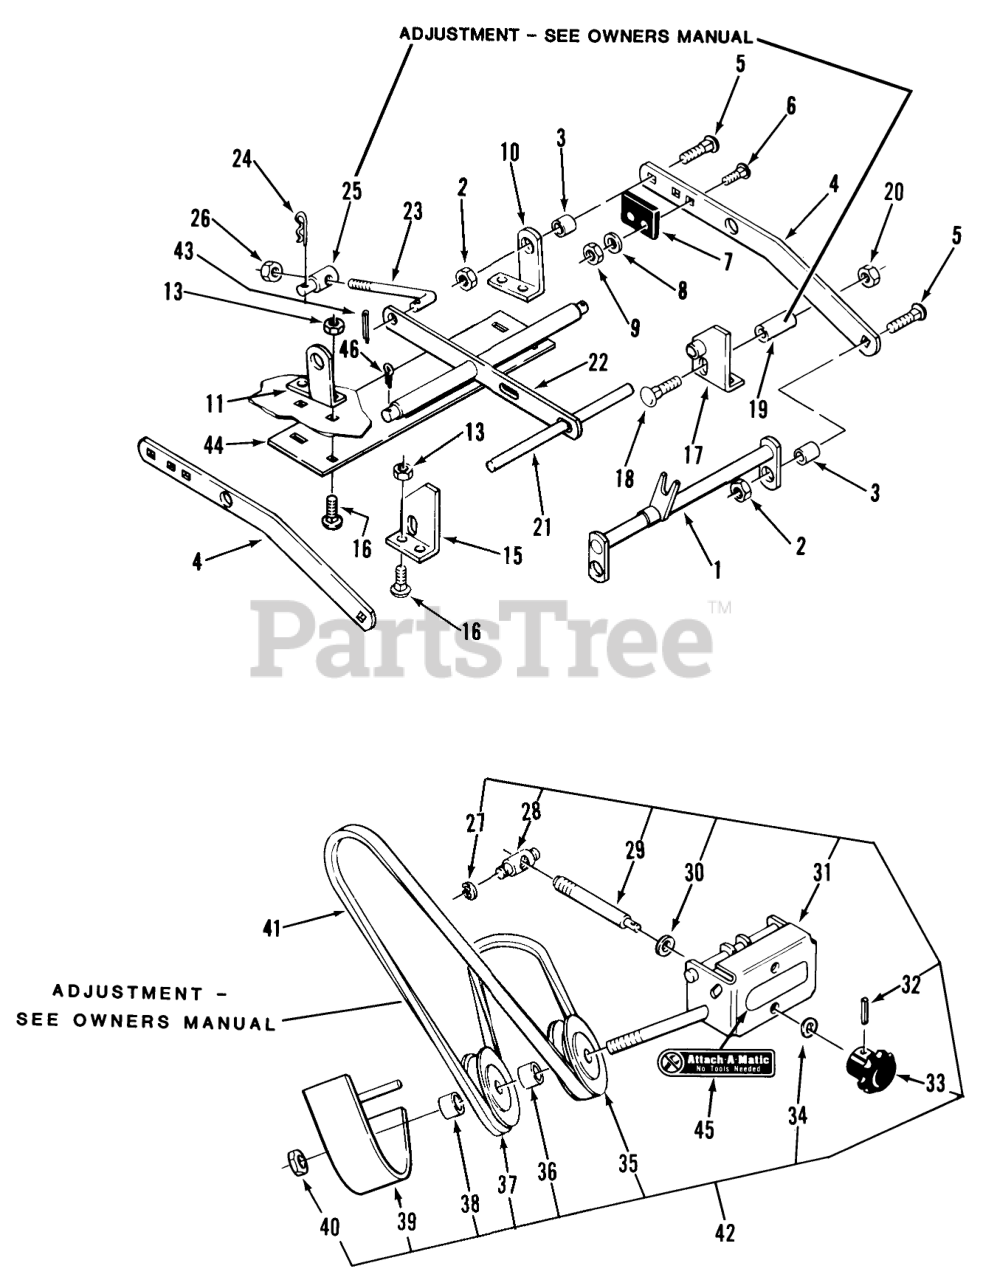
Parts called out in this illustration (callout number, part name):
1	Hitch
2	LOCKNUT-FLANGE
3	SPACER
4	Bar Draft
5	Bolt
6	Bolt-Carriage
7	BUMPER
8	Collar
9	Nut
10	LH Rear Bracket
11	Rear Bracket RH
13	NUT
15	Front Bracket RH
16	Bolt
17	Front Bracket LH
18	CARRIAGE BOLT -4
20	Nut
21	Front Shaft
22	Leveler
23	ROD-LEVEL ADJUST
24	Hairpin
25	TRUNNION-LIFT
26	NUT
27	RING-RETAINING
28	TRUNNION-DOUBLE
29	ROD ADJ
30	Washer
31	Front Support
32	PIN-ROLL
33	KNOB-ADJUSTMENT
34	WASHER-SPRING
35	Pulley-V
36	SPACER
37	PULLEY-FLAT IDLER
38	SPACER-OUTER
39	Belt Cover
40	Nut
41	V-BELT
42	ASM-SUPPORT,IDLER
43	Cotter Pin
44	PLATE R
45	Decal-Attac-O-Matic
46	Cotter Pin
